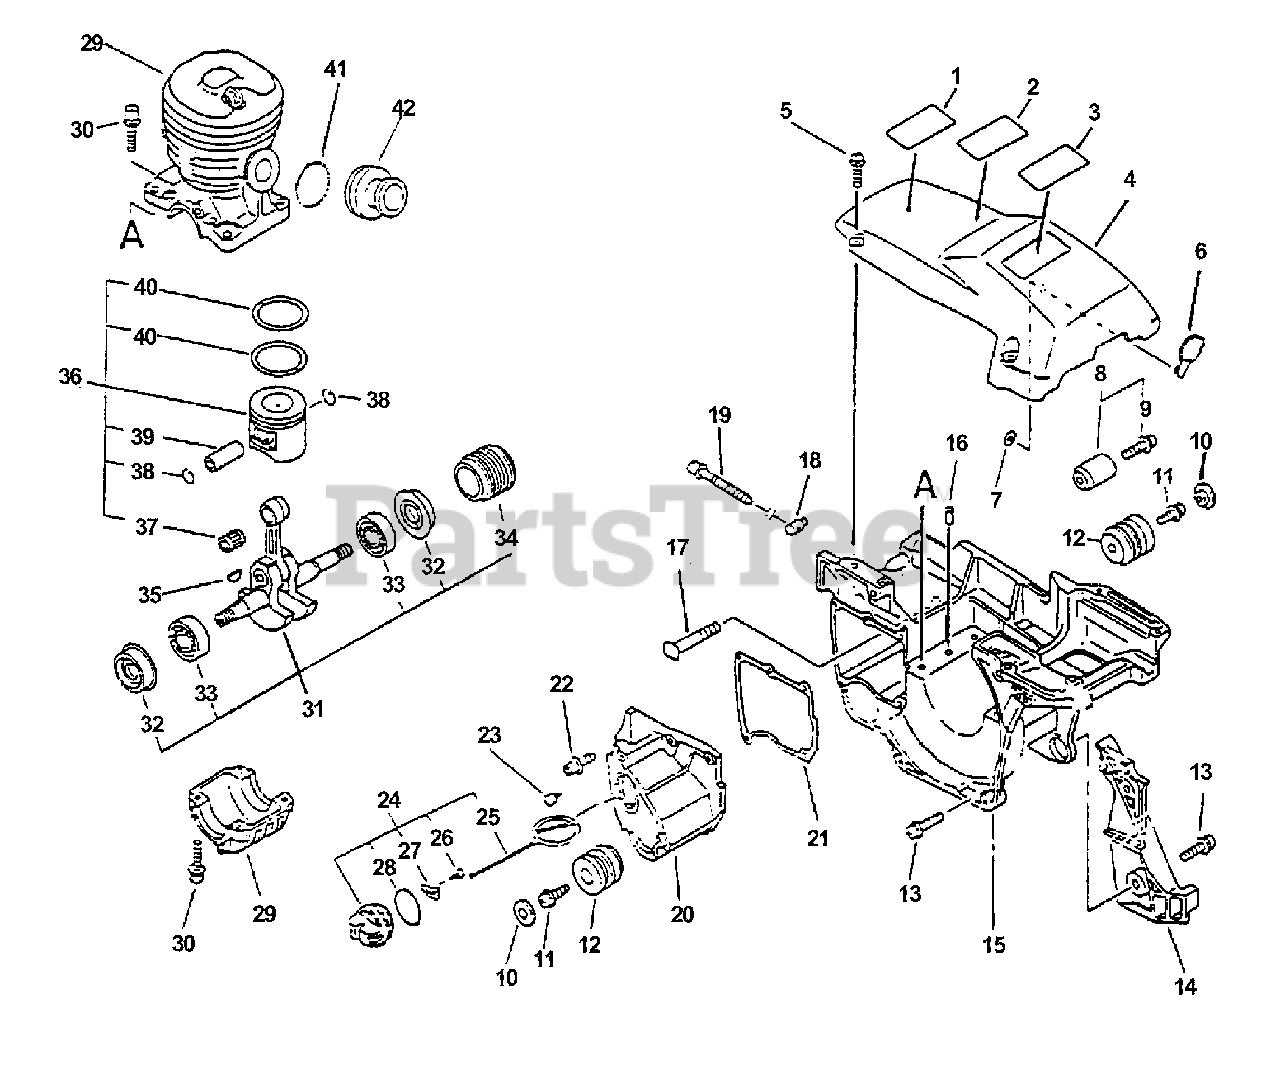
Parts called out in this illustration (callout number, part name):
1	LABEL - KICK BACK
3	LABEL, CS-4400
4	ENGINE COVER KIT
6	PLATE, WIND PROOF
7	PUSHNUT - 4
8	CHAIN CATCHER KIT
9	SCREW 5×18
10	CAP, CUSHION
12	CUSHION 5
13	SCREW 5×16
15	COVER, ENGINE
16	PIN, LOCATING 4
17	STUD, GUIDE BAR 8
18	TENSIONER, CHAIN
19	SCREW, CHAIN TENSION
20	OIL TANK ASSY
21	GASKET, OIL TANK
22	BOLT 4×16
23	VENT ASSY
24	CAP ASSY, OIL
25	CONNECTOR, CAP L= 60 MM
26	SCREW, TAPPING 3×8
27	RETAINER, CONNECTOR
29	CRANKCASE KIT
30	BOLT 5×22
31	CRANKSHAFT ASSY
32	SEAL, OIL
33	BEARING, BALL - 6201 C3
34	GEAR, WORM
35	KEY, WOODRUFF
36	PISTON KIT
37	BEARING, NEEDLE 9
38	RING, RETAINING
39	PIN, PISTON
40	RING, PISTON
42	ADAPTOR, INTAKE
